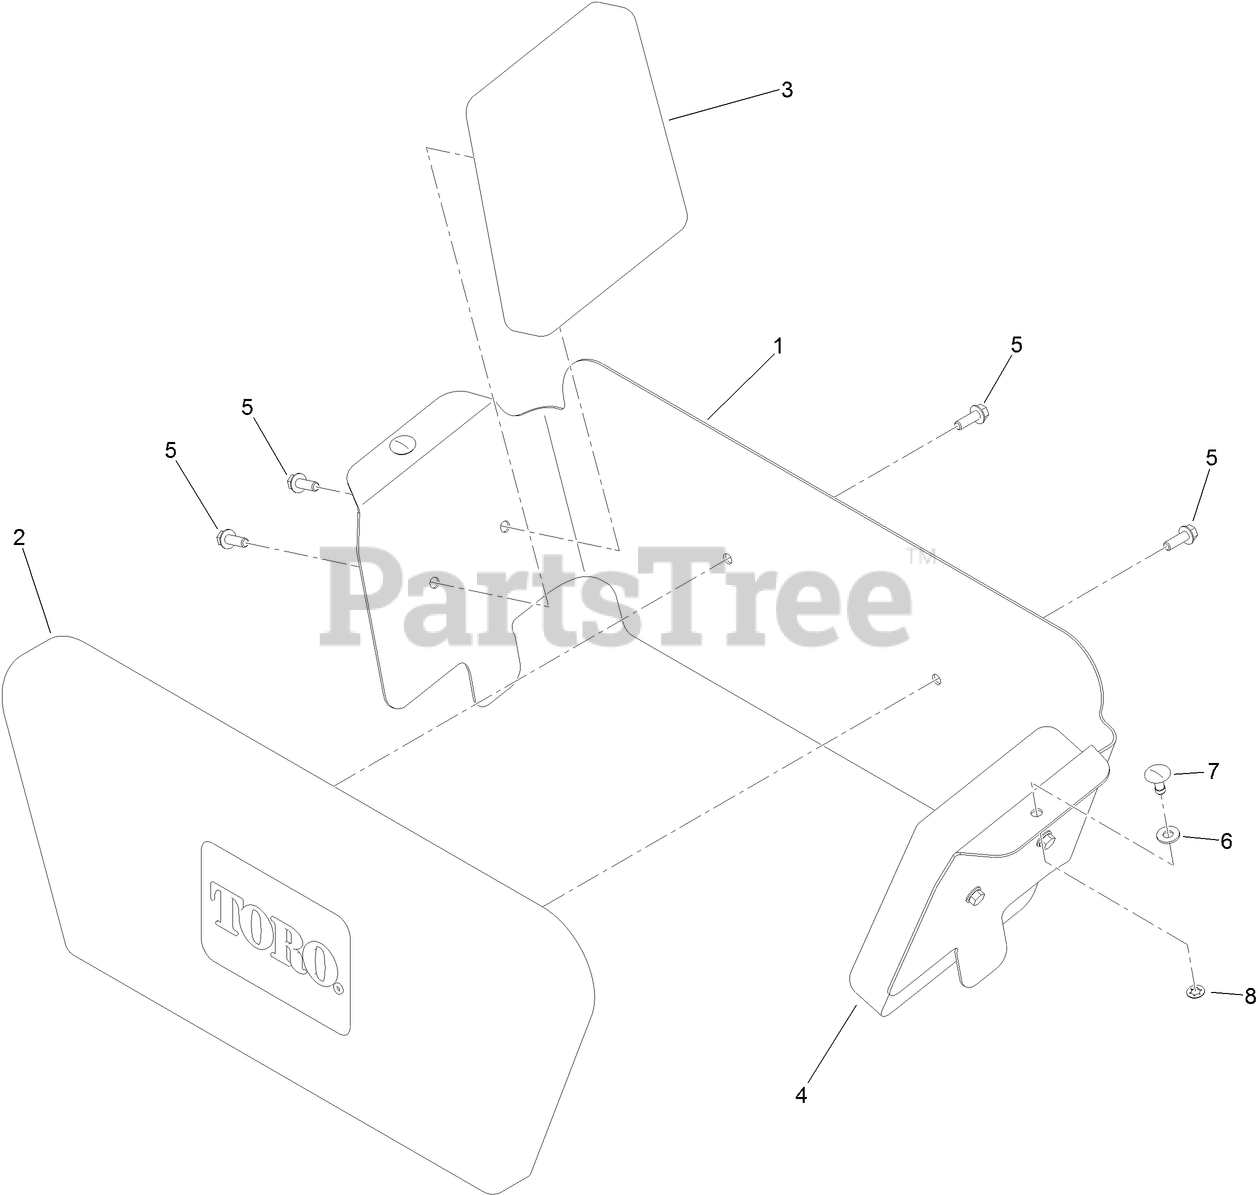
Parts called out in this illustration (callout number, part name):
1	BRACKET-PAD, KNEE
2	PAD-KNEE, CENTER
3	PAD-KNEE, SIDE (LH)
4	PAD-KNEE, SIDE (RH)
5	SCREW-HHF
6	WASHER-FLAT
7	STUD-1/4 TURN
8	RETAINER-STUD
